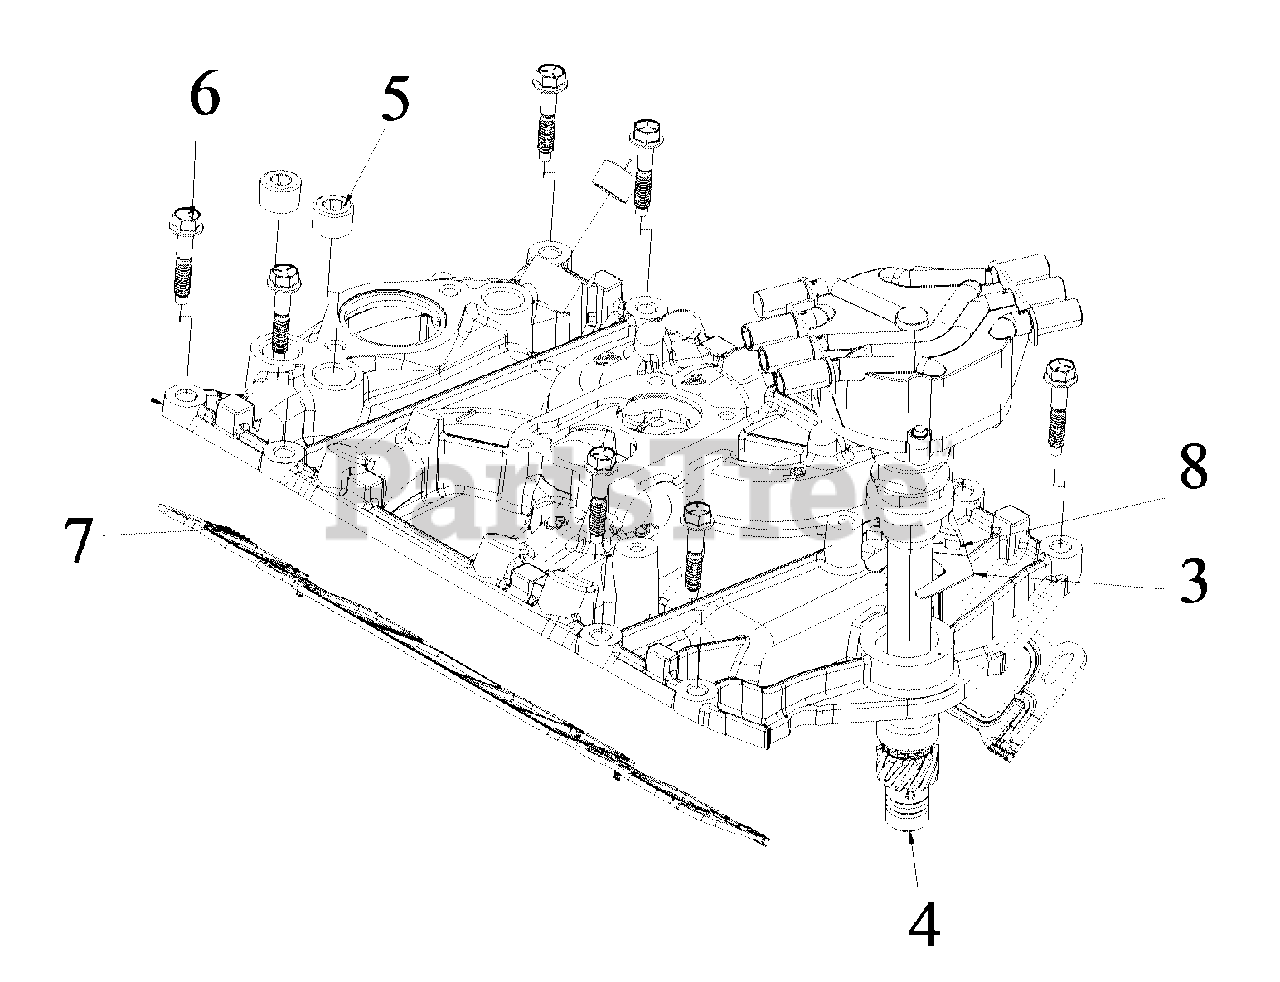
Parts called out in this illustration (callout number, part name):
3	YOLK, DIST ALGMT
4	DISTRIBUTOR
5	PLUG, 1/2" NPT
6	BOLT, INTAKE MANIFOLD
7	GASKET, INTAKE MANIFOLD
8	MANIFOLD, INTAKE
